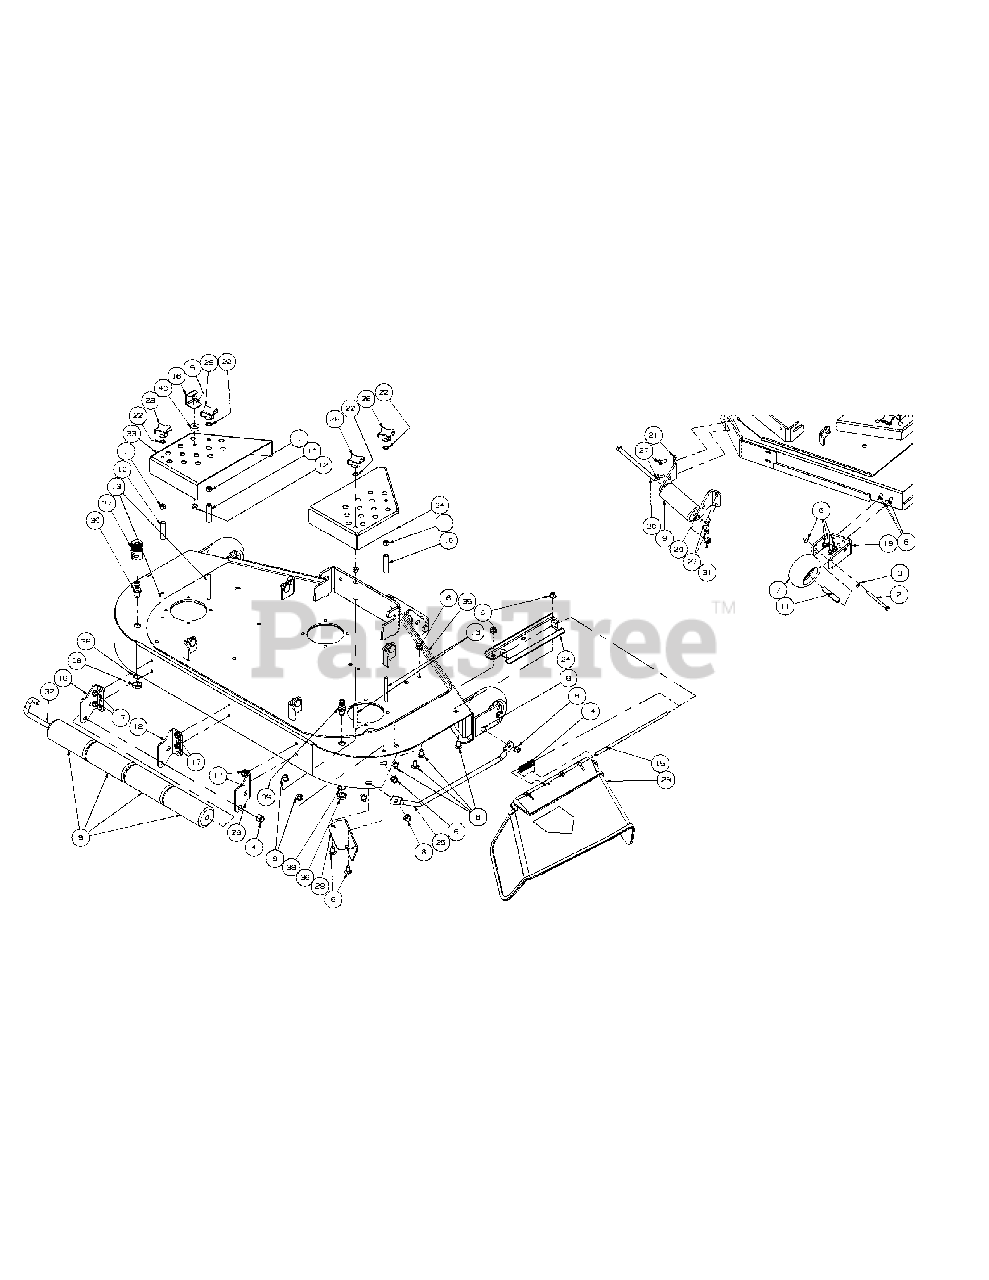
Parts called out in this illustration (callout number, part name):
1	Hex Nut 3/8-16
2	Hex Cap Screw, 3/8-16, 3.75
4	Hex Nut, 1/2-13, Insert Lock
5	Hex Cap Screw, 5/16-18, 1.00
6	Hex Nut, 3/8-16 Flange Lock
7	Complete Wheel, 5.00 Dia
8	Carriage Bolt 3/8-16 x .75
9	Front Roller
10	Spacer Stop Deck
11	Wheel Spacer
12	Hex Nut, 5/16-18 Flange Lock
13	Carriage Bolt, 3/8-16 x 3.5 Lg
14	Torsion Spring
15	Chute Deflector Rod
16	Stop Bracket
17	Self Tapping Screw, 5/16-18 x 1/2
18	Fabricted Deck Roller Mount Bracket
19	Front Anti-Scalp Wheel Mount Bracket
22	External Washer, 3/8
23	Deflector Chute
24	Deflector Chute Bracket
25	Fabricated Deck Finger Guard
26	Grass Catcher Roller Bracket
27	Self Tapping Screw, 3/8-16 x 0.875
28	Plastic Knob
29	Fabricated Deck, Chute Bracket
30	Hex Cap Screw, 1/2-20 x 7.25
31	Lock Nut, Nylon Insert, 1/2-20
32	J-Hook w/ Threaded Roller
33	Belt Cover, LH
34	Belt Cover, RH
35	44 Fabricated Deck Assembly
36	Hex Nut, M16-1.5
37	Water Nozzle Adaptor
38	Lock Washer, 17 x 23.8 x 1.95
39	Deck Water Nozzle
40	Spacer .406 ID x 1.0 OD
